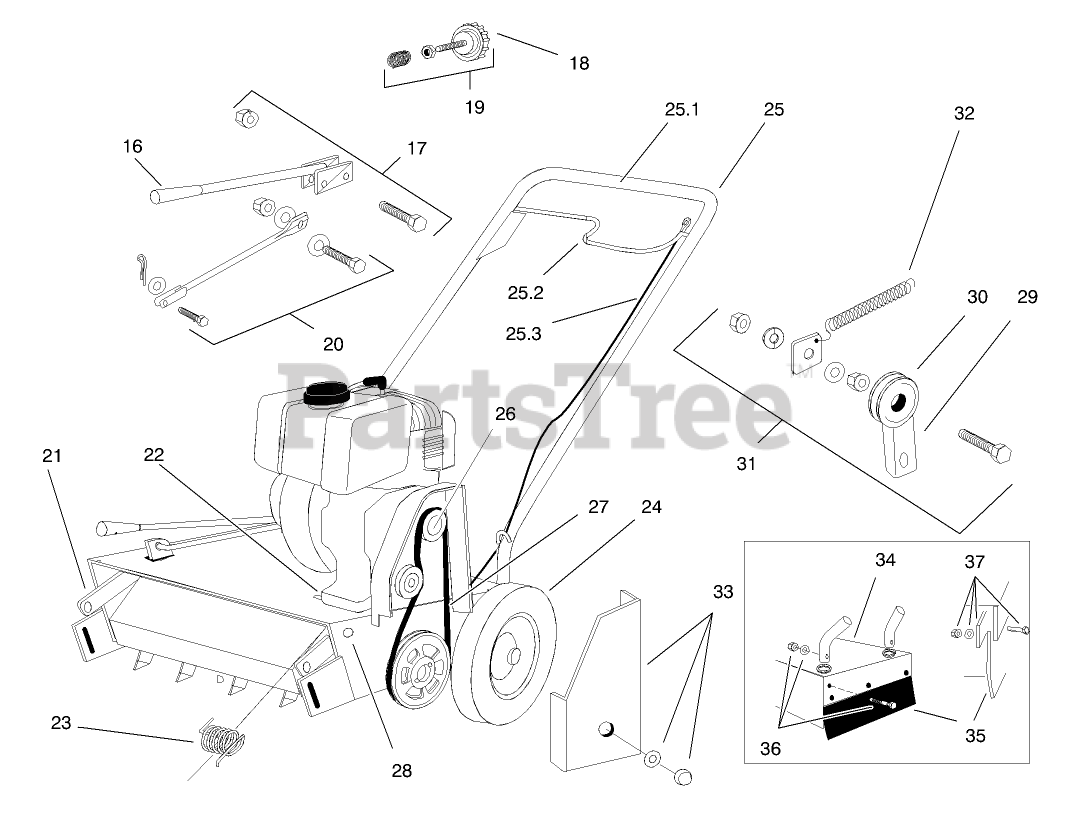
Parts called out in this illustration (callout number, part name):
16	KNOB
17	KIT - LEVER
18	KNOB
19	KIT - HEIGHT ADJUSTMENT
20	KIT - PUSH ROD
21	ARM - TORQUE
22	PLATE
23	SPRING
24	WHEEL
25	HandleAsm.(Incl. Ref. #25.1, 25.2, 25.3)
25.1	HANDLE
25.2	HANDLE - CLUTCH
25.3	CABLE - CLUTCH
26	V-PULLEY
27	V-BELT
28	KIT - ROD TRUNNION
29	ARM - MOUNTING
30	PULLEY
31	PulleyAsm. w/Hardware(Incl. Ref. #29, 32, 30)
32	SPRING - CLUTCH
33	ASSEMBLY - SHIELD
34	WA - HOUSING
35	DEFLECTOR
36	KIT - BOLT
37	KIT - STRAP
